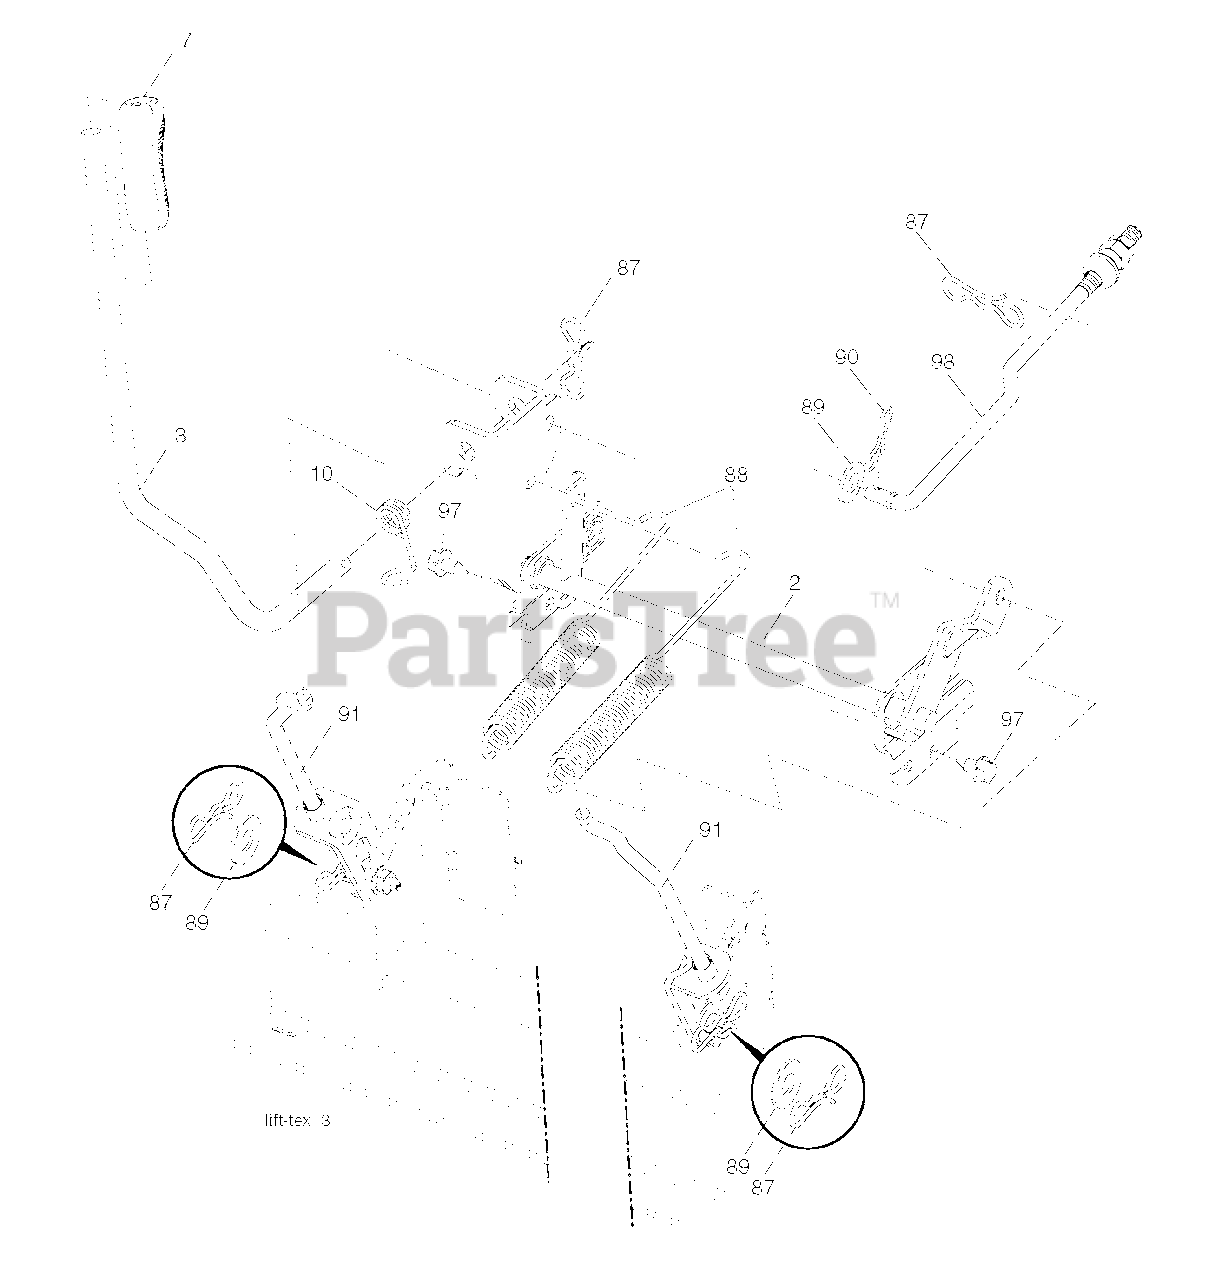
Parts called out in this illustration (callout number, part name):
2	SHAFT.ASM.CROSS.LIFT
3	LEVER.LIFT.HANDLE.GT
7	GRIP.HANDLE.LIFT.PVC.BLACK
10	SPRING.TORSION.LIFT.HANDLE
87	PIN.COTTER.7/16.BOW TI.
88	SPRING.LIFT.ASSIST.GT2
89	WASHER.CLEAR.ZINC
90	PIN.COTTER.5/16.BOW TI
91	LINK.LIFT.ASM.REAR.GT.
97	SCREW, 3/8-16X3/4
98	LINK.ASM.SUSP.FRONT.MWR.10.5
